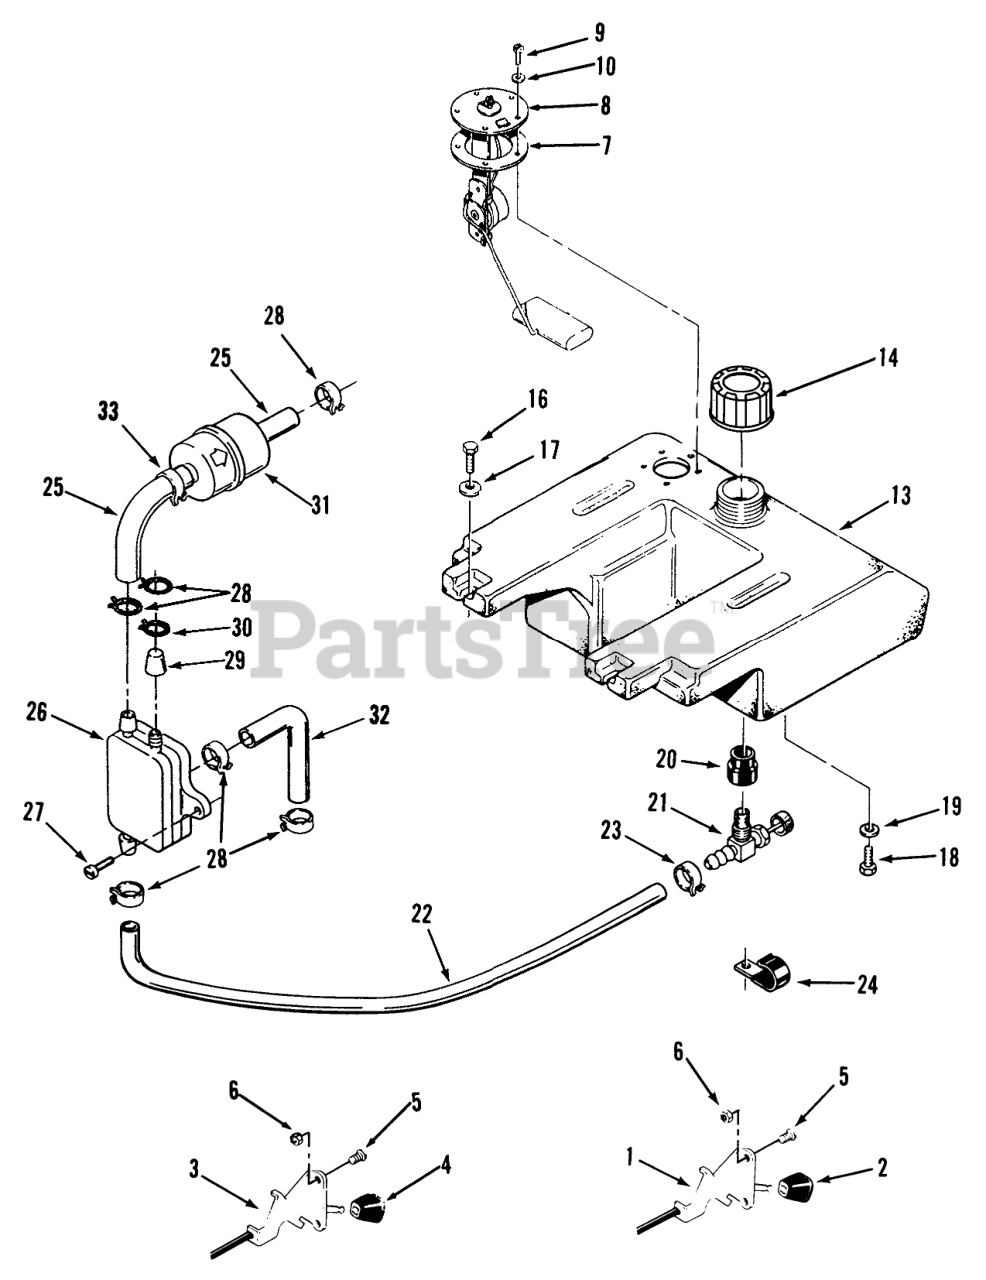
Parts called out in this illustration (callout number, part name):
1	CONTROL-THROTTLE
2	KNOB-CONTROL
3	CONTROL-CHOKE
4	KNOB-CONTROL
5	SCRW-PHC
6	Nut
7	GASKET-SENDER, FUEL
8	SENDER-FUEL LEVEL
9	Screw
10	Lockwasher
13	Fuel Tank (Includes items 20 & 21)
14	GAS CAP ASM
16	Bolt
17	WASHER-FLAT
18	Bolt
19	WASHER-LOCK
20	BUSHING
21	VALVE-FUEL
22	Line-Fuel 53"
23	Clamp
24	Clamp
25	Hose
26	Fuel Pump
27	SCREW-TAPPING PAN HD
28	CLAMP-HOSE
29	CAP-FUEL OUTLET
30	CLAMP
31	Filter-Fuel
32	Hose
33	CLIP-WIRE
